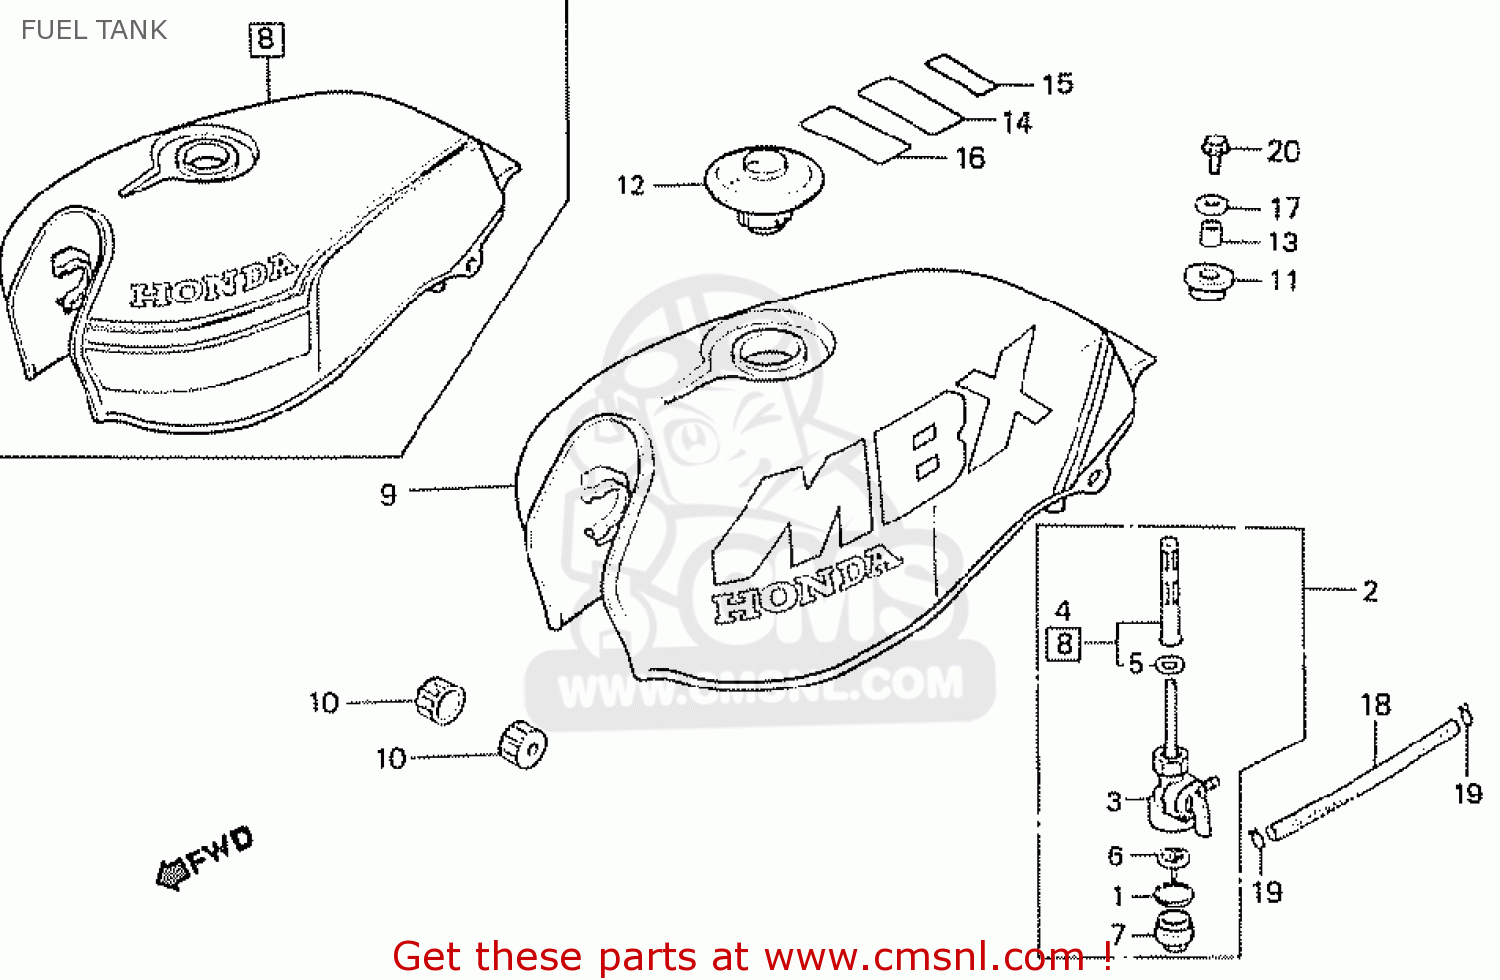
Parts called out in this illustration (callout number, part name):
1	O-RING , FUEL STRAIN
2	COCK ASSY,FUEL
3	BODY COMP.,COCK
4	SCREEN SET,F/STRA
5	O-RING
6	FILTER,CUP
7	CUP,FUEL STRAINER
8	TANK SET*NH-1*
10	CUSHION,TANK FR.
11	CUSH,FUEL TANK RR
12	CAP,FUEL FILLER
13	COLLAR,TOP BRIDGE
14	MARK,DRIVECAUTION
15	MARK.A.OIL*TYPE1*
17	WASHER,8MM
18	TUBE,FUEL 4.5X120
20	BOLT FLANGE 8X25
